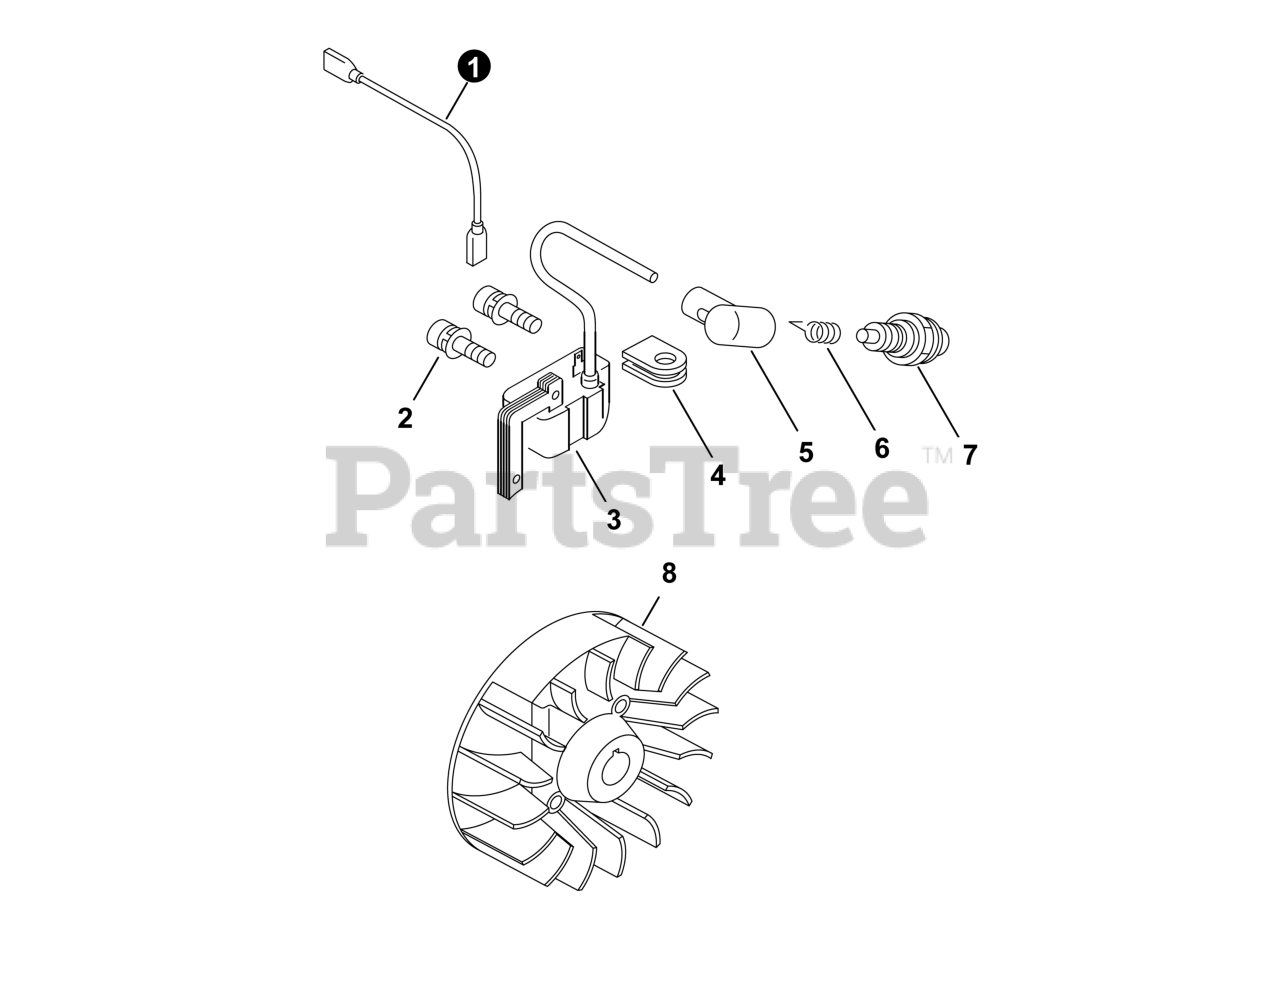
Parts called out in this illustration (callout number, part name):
1	LEAD - IGNITION
2	SCREW 4x22
3	COIL, IGNITION
5	CAP, SPARK PLUG
6	TERMINAL, SPARK PLUG
7	SPARK PLUG - BPMR7A
8	FLYWHEEL
